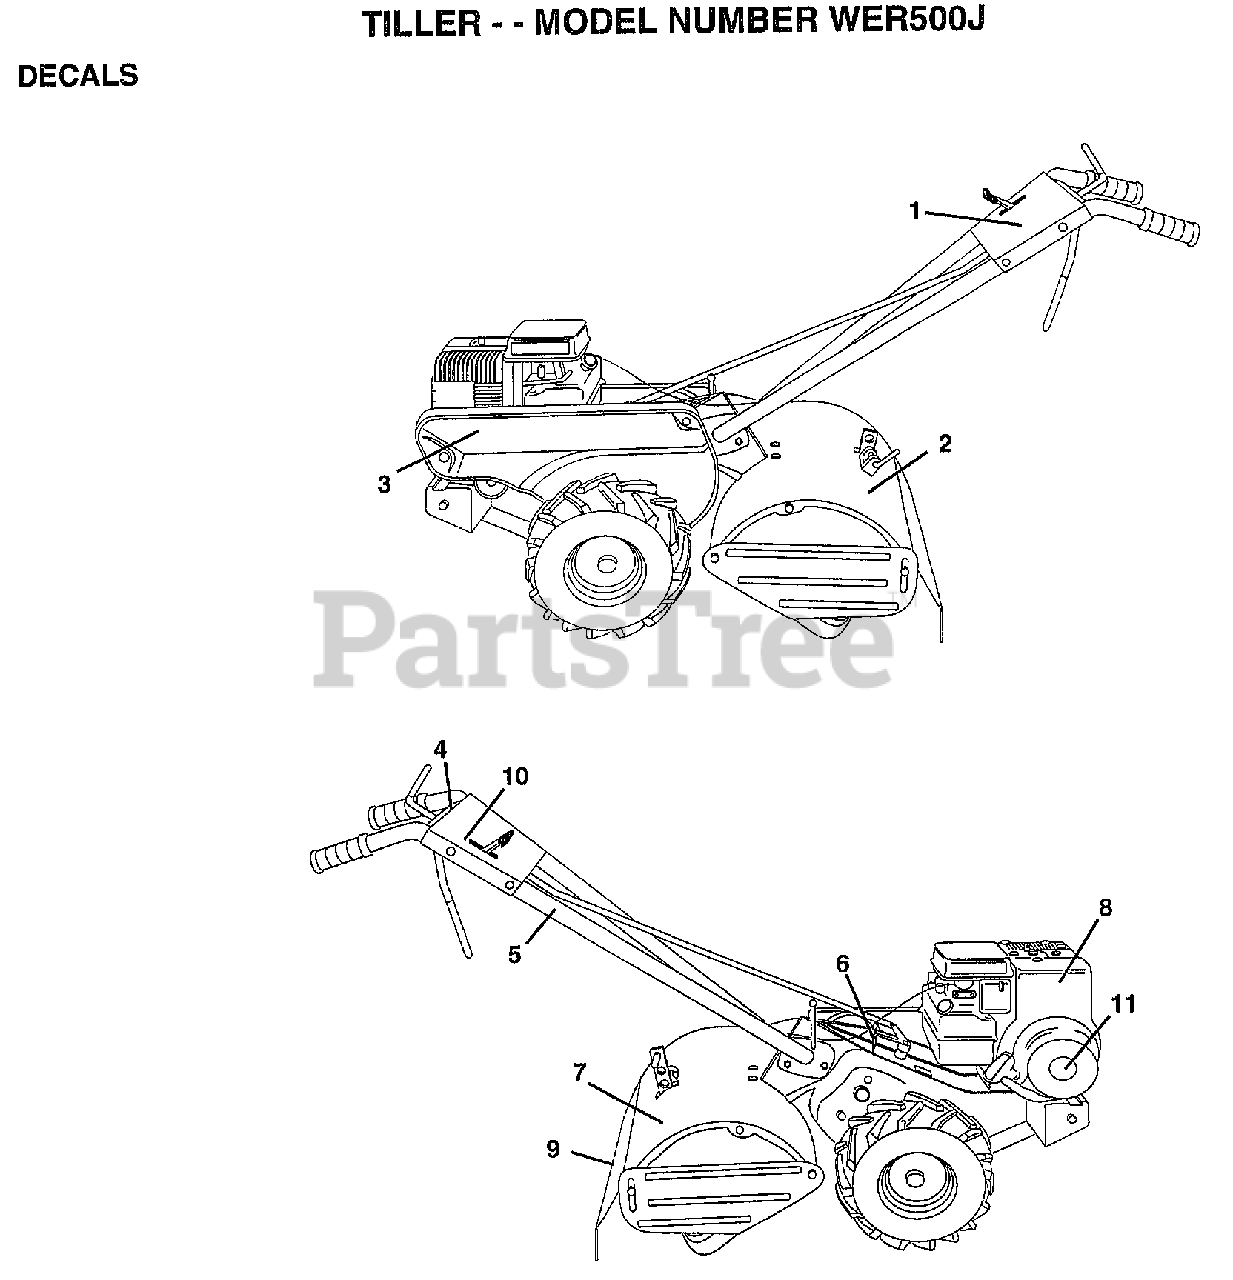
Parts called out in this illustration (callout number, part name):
2	DECAL.DESCRIPTION
5	DECAL TI
6	DECAL CRT
7	DECAL.CAUTION
8	DECAL, BRIGGS & STRATTON
10	DECAL REVERSE
